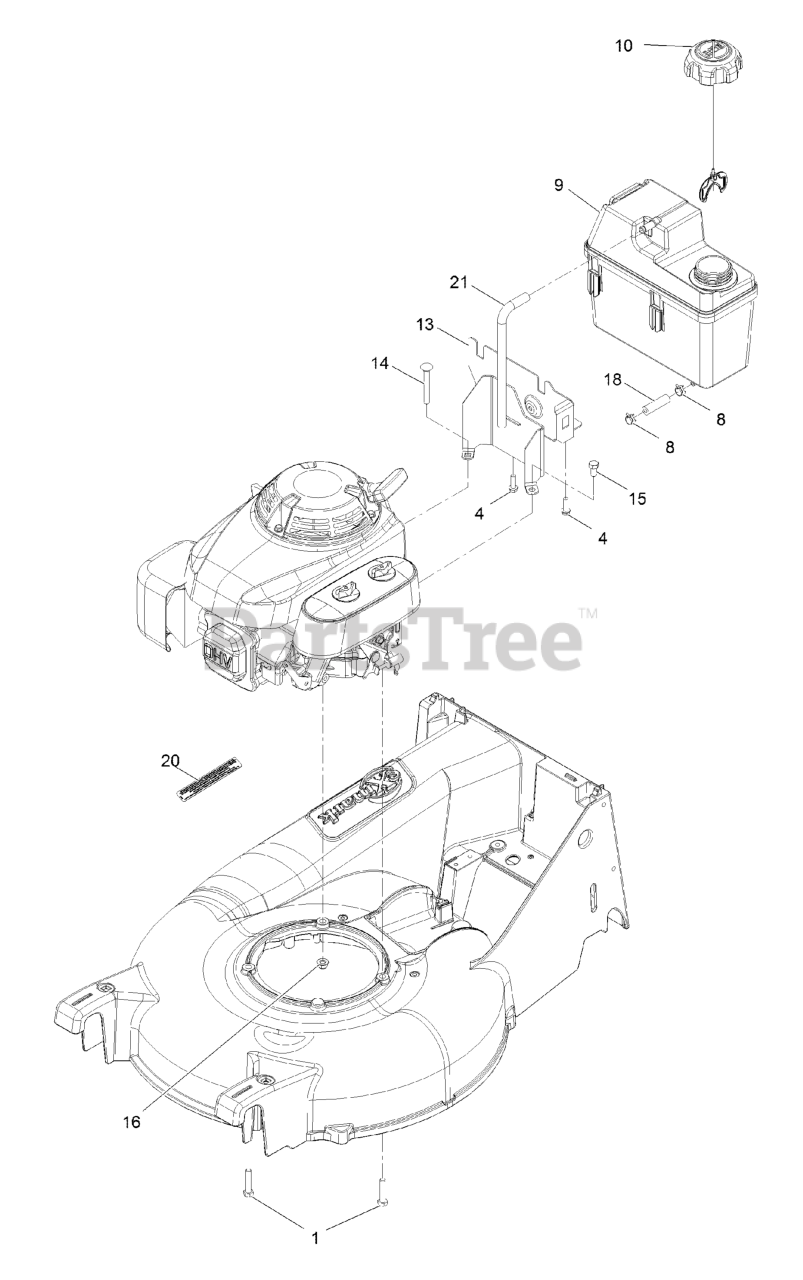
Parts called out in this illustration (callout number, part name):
1	SCREW-HH
4	SCREW-HWH
8	CLAMP-HOSE
9	TANK-FUEL
10	CAP-FUEL
13	BRACKET ASM
14	SCREW-CARR
15	SCREW-HH
16	NUT-HF, NI
18	HOSE-FUEL
20	DECAL-ARRESTOR, SPARK
21	HOSE-VENT, CANISTER
